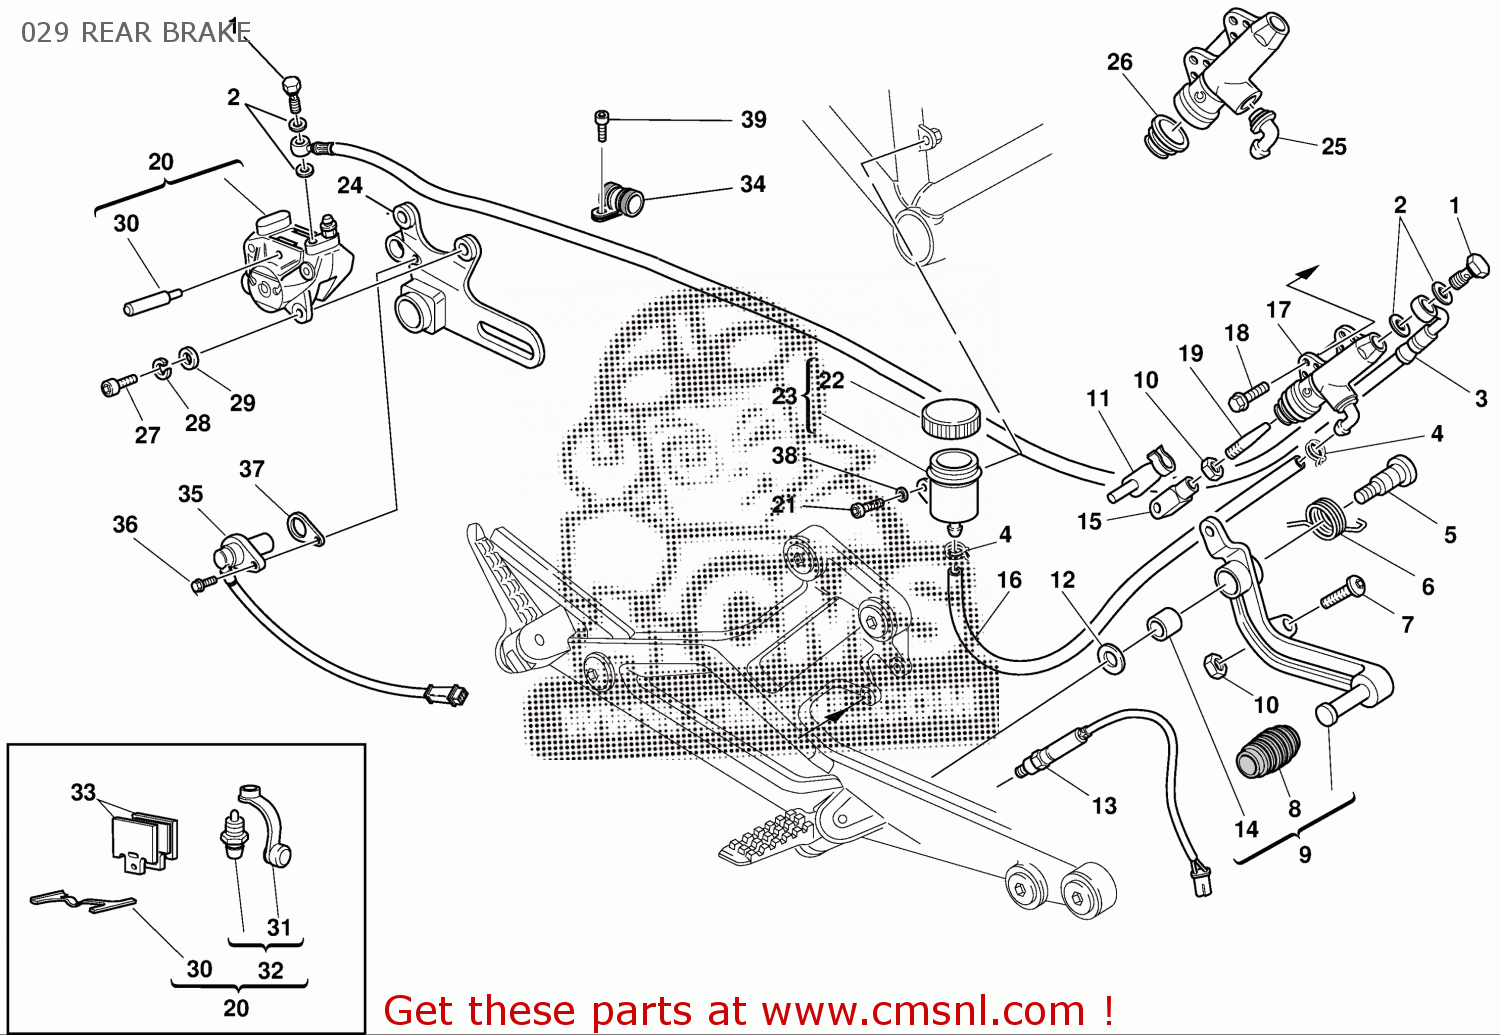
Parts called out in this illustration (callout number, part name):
1	BOLT, BRAKE HOSE
2	COPPER GASKET 11.9X8.2X2
3	REAR BRAKE HOSE
4	CLAMP
5	PIN PEDAL
6	SPRING
7	SCREW, SPECIAL
8	RUBBER PAD
9	PEDAL, BRAKE
10	NUT
11	SPRING
12	WASHER
13	SWITCH, REAR BRAKE
14	BUSH
15	YOKE
16	HOSE, OIL
17	REAR BRAKE PUMP
18	SCREW M6X20
19	ROD, BRAKE
20	REAR BRAKE CALIPER
21	BOLT.HEXAGON SOCKET HEAD M6X10
22	CLUTCH BRAKE PUMP COVER KIT
23	RESERVOIR, BRAKE FLUID
24	BRACKET, REAR CALIPER
25	JOINT, HOSE
26	DUST COVER
27	SCREW M8X25
28	WASHER, SPRING
29	WASHER
30	PAD PINS OVERHAUL KIT
31	DUST PLUG
32	BREATHER VALVE
33	REAR BRAKE PADS SET
34	HOSE CLAMP 8 MM
35	SENSOR, SPEED
36	SCREW
37	SPACER
38	WASHER
39	SCREW TE M5X0.8X16 CH8
